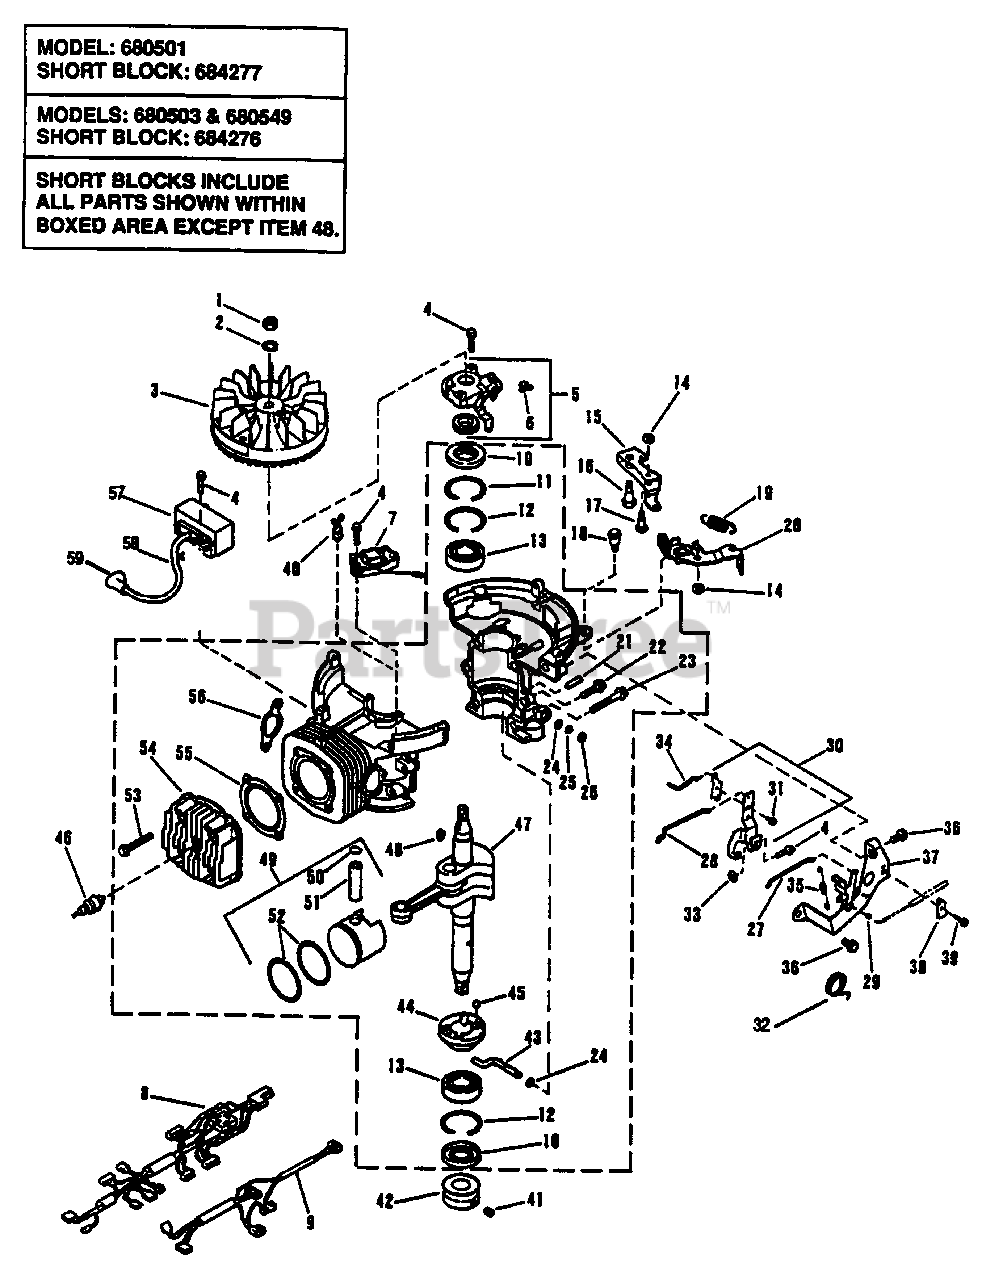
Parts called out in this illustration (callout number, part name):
1	Nut-Flywheel
2	Lockwasher
3	Flywheel (680503 & 680549)
4	Screw (680503)
5	Oil Pump Kit w/Oil Lines (Inc. 6)
6	Clamp-Oil Line
7	Alternator (680503)
8	Wire Harness (680503)
9	Wire Harness (680501)
10	Oil Seal-Crankshaft
11	Retaining Ring
12	Retaining Ring
13	Bearing-Crankshaft
14	Nut (680503 & 680549)
15	Brake Actuator (680503 8680549)
16	Shoulder Bolt (680501)
17	Shoulder Bolt (680503 & 680549)
18	Shoulder Bolt (680503 & 680549)
19	Brake Spring (680503 & 680549)
20	Brake & Switch (680503 &680549)
21	Taper Pin
22	Screw
23	Screw
24	Washer-Governor Shaft
25	Retainer Ring-Governor Shaft
26	Oil Seal-Governor Shaft
27	Choke Rod
28	Throttle Rod
29	Throttle Wire Retainer
30	Governor & Oil Pump Lever Kit (Inc. 31)
31	Screw
32	Torsion Spring
33	Nut
34	Oil Pump Control Rod
35	Governor Spring
36	Screw
37	Governor Bracket Assy (680503 & 680549) (Inc. 32)
38	Clamp-Throttle Cable to Bracket
39	Screw
40	Wire Tie (680501)
41	Set Screw-Engine Pulley
42	Engine Pulley
43	Governor Shaft
44	Governor Ramp
45	Ball-Governor
46	Spark Plug
47	Crankshaft & Connecting Rod (680503 & 680549)
48	Key (680503 & 680549)
49	Piston & Ring Assy. (Standard) (Inc. 50-52)
50	Retaining Ring
51	Wrist Pin
52	Ring Set (Standard)
52	Ring Set (0.020" Oversize)
53	Screw-Cylinder Head to Block
54	Cylinder Head
55	Head Gasket
56	Exhaust Gasket
57	C.D. Ignition Modulel (Inc. 58-59)
58	High Tension Lead & Cvr (Inc. 59)
59	Cover & Terminal Assembly
